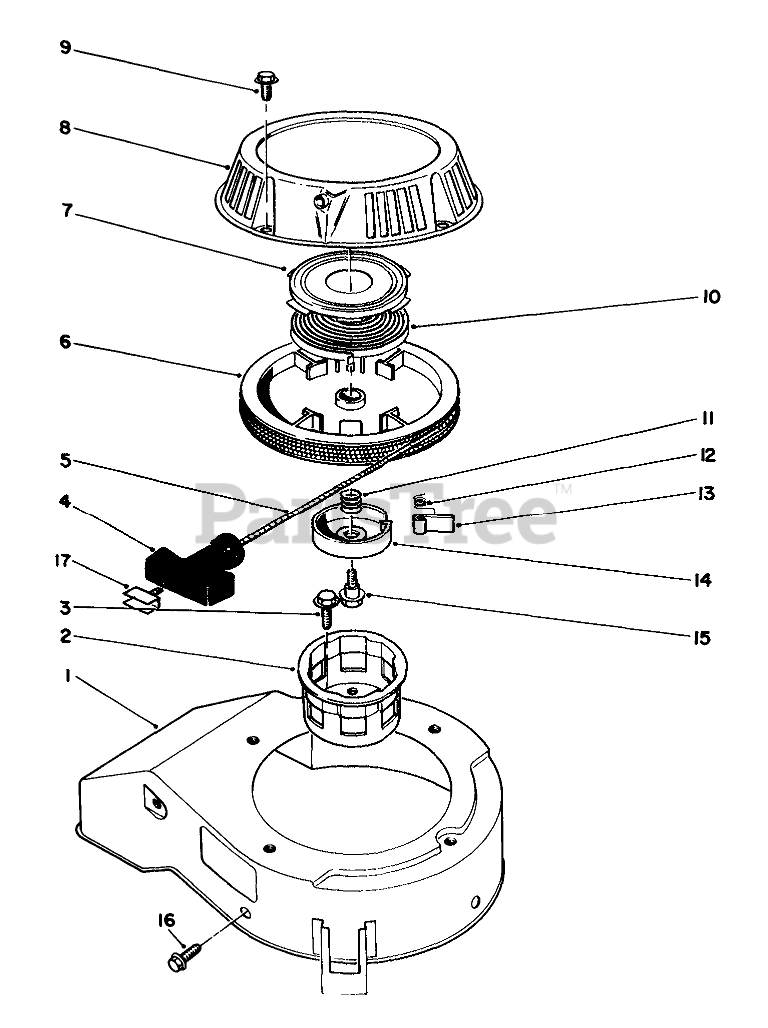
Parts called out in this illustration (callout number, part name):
1	Cover-Cooling Fan
2	PULLEY-CUP, STARTER
4	HANDLE-RECOIL
5	ROPE-STARTER
7	Retainer-Recoil Spring
8	CASE-STARTER
9	SCREW-HHF
10	Spring-Recoil
11	SPRING
12	SPRING
14	RETAINER
17	Insert Handle
